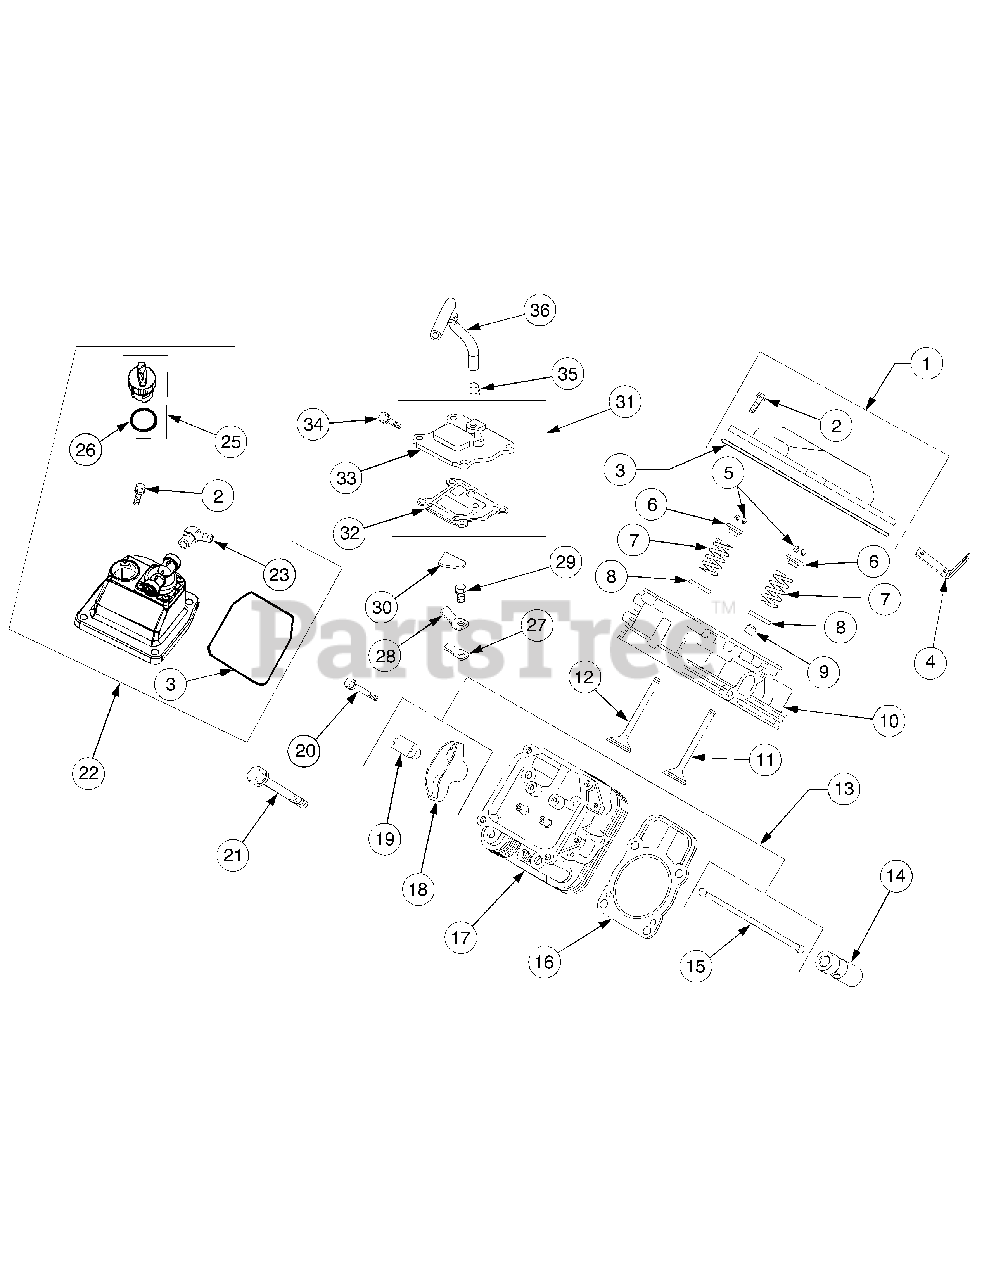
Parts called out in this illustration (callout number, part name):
1	Kit, Valve Cover (Includes 2-3)
2	Screw, Hex Flng, M6 x1.0 x 30
3	O-Ring, Valve Cover
4	Strap, Lifting
5	Kit, Retainer
6	Cap, Valve Spring
7	Spring, Valve
8	Retainer, Spring
9	Seal, Valve Stem
10	Head Assembly, #1 Cylinder
11	Valve, Intake Std
11	Valve, Intake, .25mm
12	Valve, Exhaust Std
12	Valve, Exhaust, .25mm
13	Kit, Valve Train (Incl. 15,18,19)
14	Lifter, Valve
16	Kit, Cyl. Hd. Gasket (Includes 21)
17	Head Assembly, #2 Cylinder
19	Pivot, Rocker Arm
20	Screw, Hex Flng, M6 x 1.0 x 34
21	Screw, Hex Flng, M10 x 1.5 x 90
22	Kit, Fuel Pump Valve Cover
23	Fitting, 90°
25	Cap Assembly, Oil Fill (Incl. 26)
26	O-Ring
27	Reed, Breather
28	Retainer, Breather Reed
29	Screw, Hex Flng, M5 x 0.8 x 10
30	Filter, Breather
31	Kit, Breather (Includes 32-34)
32	Gasket, Breather
33	Cover, Breather
34	Screw, Hex Flng M6 x 1.0 x 20
35	Clamp, Breather
36	Hose, Breather
